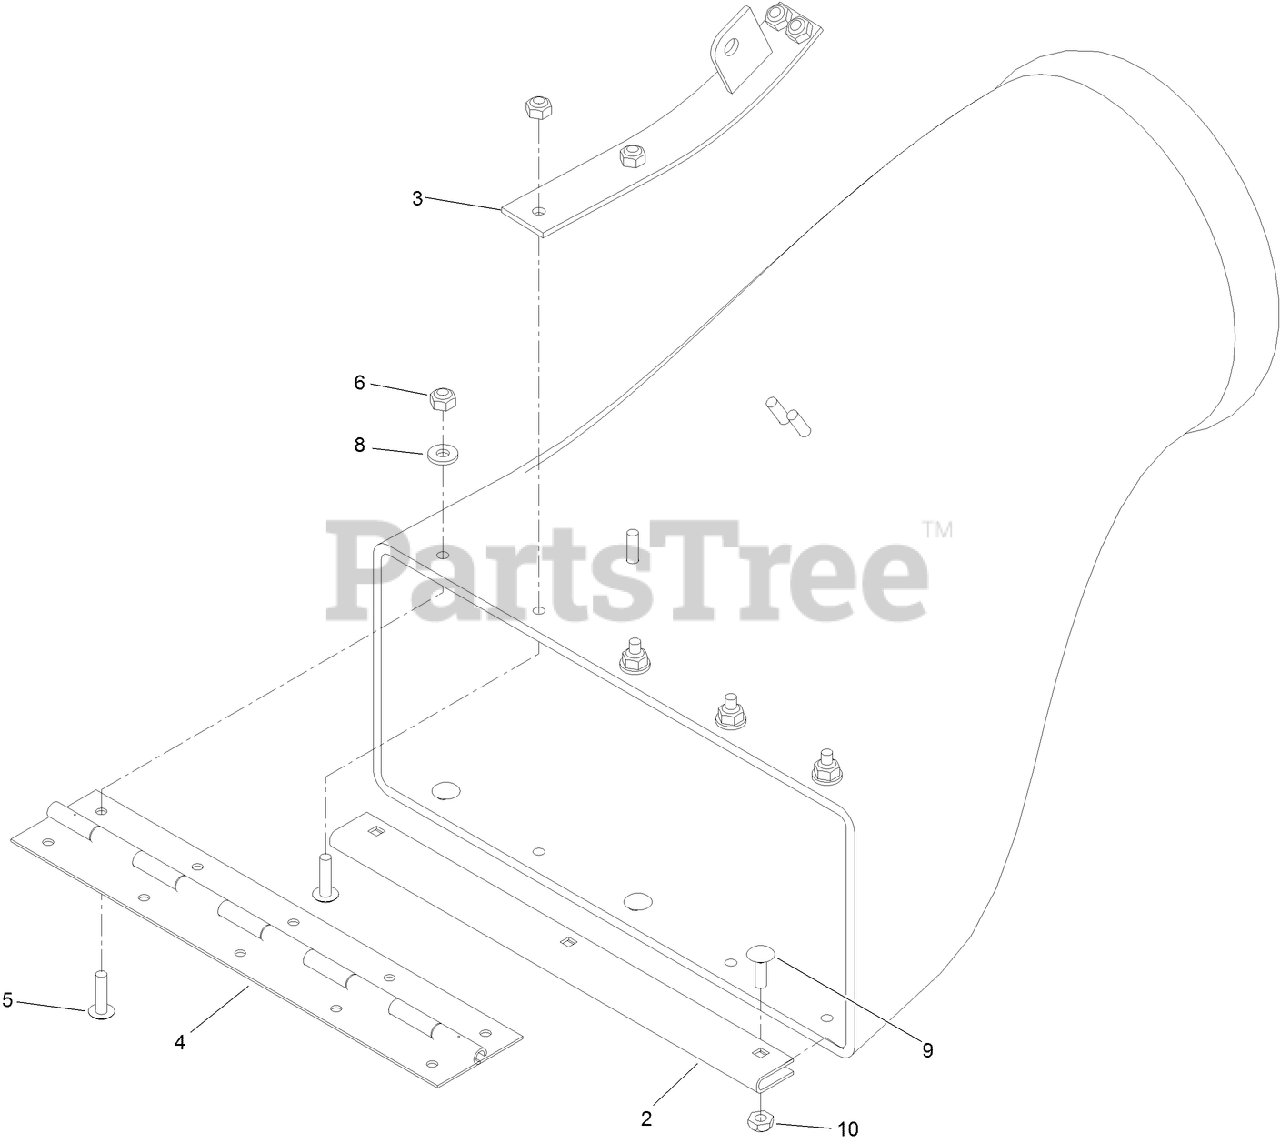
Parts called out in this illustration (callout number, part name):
2	GUARD-PLENUM
3	MOUNT-SPRING
4	HINGE-PIANO
5	SCREW-HEAD, TRUSS
6	NUT-LOCK, NI
8	WASHER-FLAT
9	BOLT-CARR
10	NUT-LOCK, NI
